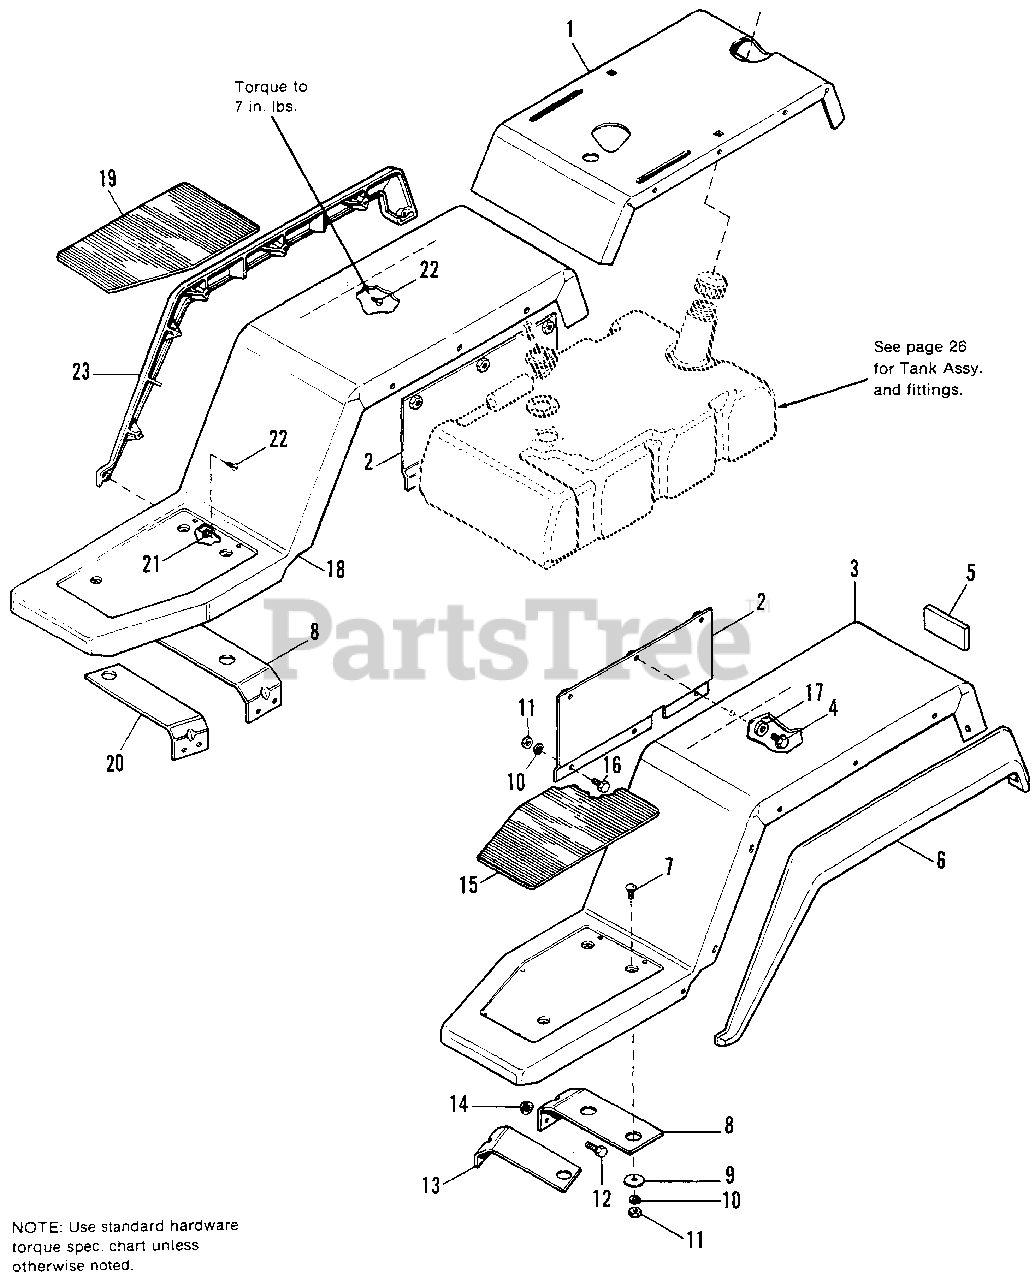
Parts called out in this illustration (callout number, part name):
1	COVER, Fuel Tank
2	FENDER SUPPORT ASSY.
3	FENDER, L.H.
4	SCREW, Taptite, 5/16-18 x 3/4
5	REFLECTOR, Rear
6	FENDER SKIRT, L.H.
7	BOLT Carriage, 5/16-18 x 3/4
8	FOOTREST SUPPORT, Rear
9	WASHER, Flat, 11/32 x 1-1/2 x 7/64
10	LOCKWASHER, 5/16
11	NUT, 5/16-18
12	CAPSCREW, Hex Hd., 3/8-16 x 7/8
13	FOOTREST SUPPORT, Front, L.H.
14	LOCKNUT, Whiz, 3/8-16
15	PAD, Footrest, L.H.
16	CAPSCREW, Hex Hd., 5/16-18 x 3/4
18	FENDER, R.H.
19	PAD, Footrest, R.H.
20	FOOTREST SUPPORT, Front, R.H.
21	LOCKWASHER, 1/4
22	SCREW, Plastite, 1/4-10 x 5/8
23	FENDER SKIRT, R.H.
